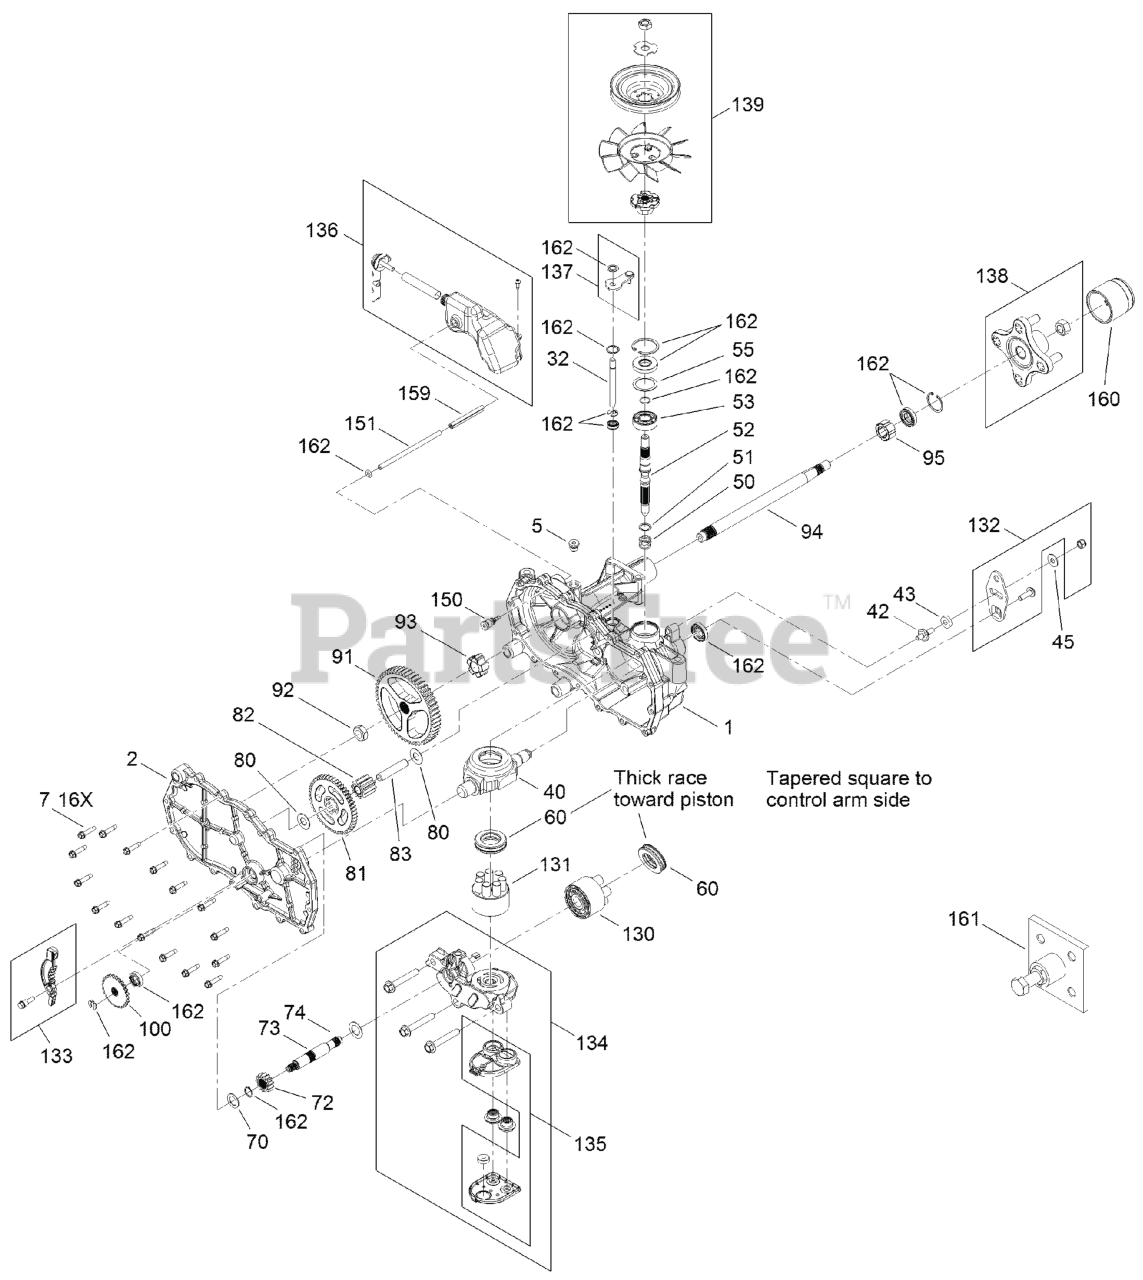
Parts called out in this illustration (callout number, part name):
1	MAIN HOUSING ASM
2	HOUSING SIDE KIT
5	PLUG-THREAD, STRAIGHT
7	SCREW-HHF
32	ROD-BYPASS
40	SWASHPLATE-TRUNNION
43	PUCK-FRICTION
52	SHAFT-INPUT
53	BEARING-BALL
60	BEARING-THRUST
70	WASHER-FLAT
72	GEAR-PINNION, 13T
73	SHAFT-MOTOR
80	Washer
81	GEAR-10T/48T
82	GEAR-JACKSHAFT, 10T
83	PIN-JACKSHAFT
91	GEAR-BULL
93	BUSHING-INBOARD
94	SHAFT-AXLE
95	BEARING-SLEEVE
100	DISC-BRAKE, COG
130	CYLINDER BLOCK KIT
131	PUMP BLOCK ASM
132	CONTROL ARM KIT
133	BRAKE ARM KIT
134	CENTER SECTION FILTER KIT
135	FILTER KIT
136	LH EXPANSION TANK KIT
137	BYPASS ARM KIT
138	HUB KIT
139	FAN PULLEY KIT
150	FITTING-SAE
159	CASE-TUBE
160	CAP-AXLE
162	SEAL AND RING KIT
